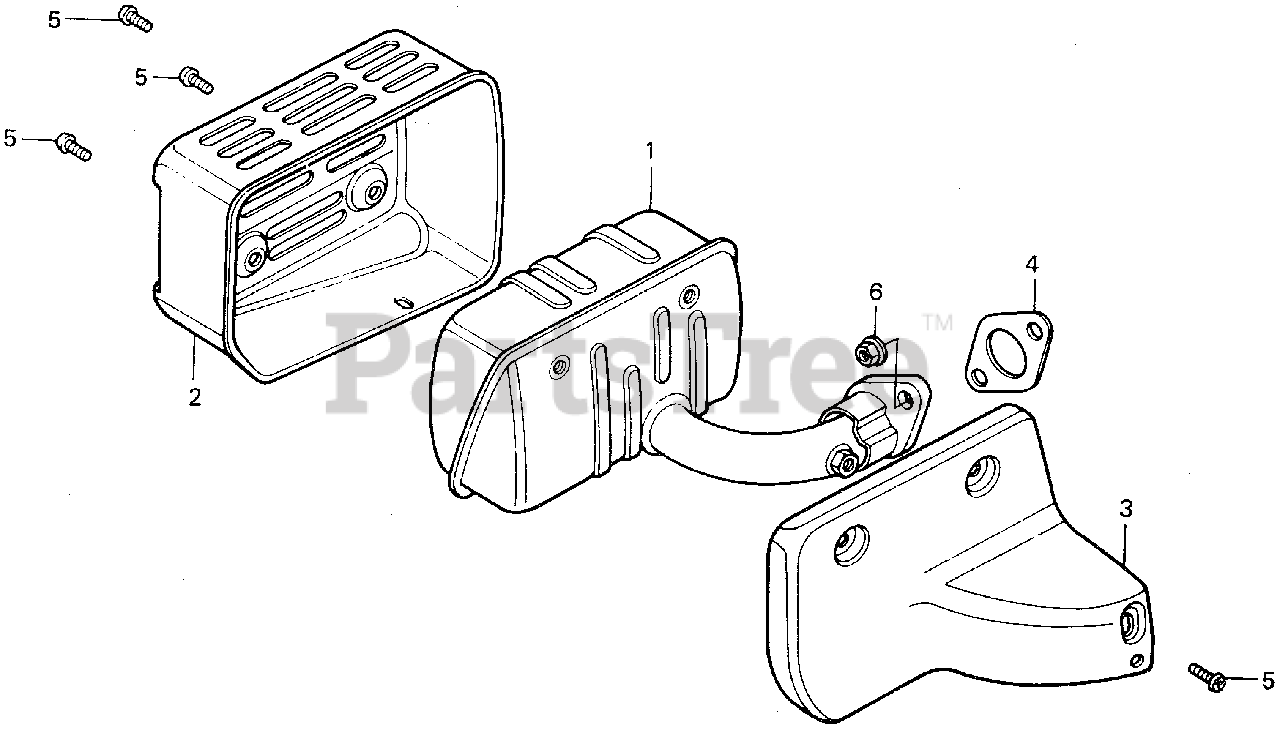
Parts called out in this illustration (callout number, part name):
2	PROTECTOR, MUFFLER
3	SEPARATOR, MUFFLER
4	GASKET, MUFFLER
5	SCREW, PAN (6X6)
6	NUT, FLANGE (8MM)
